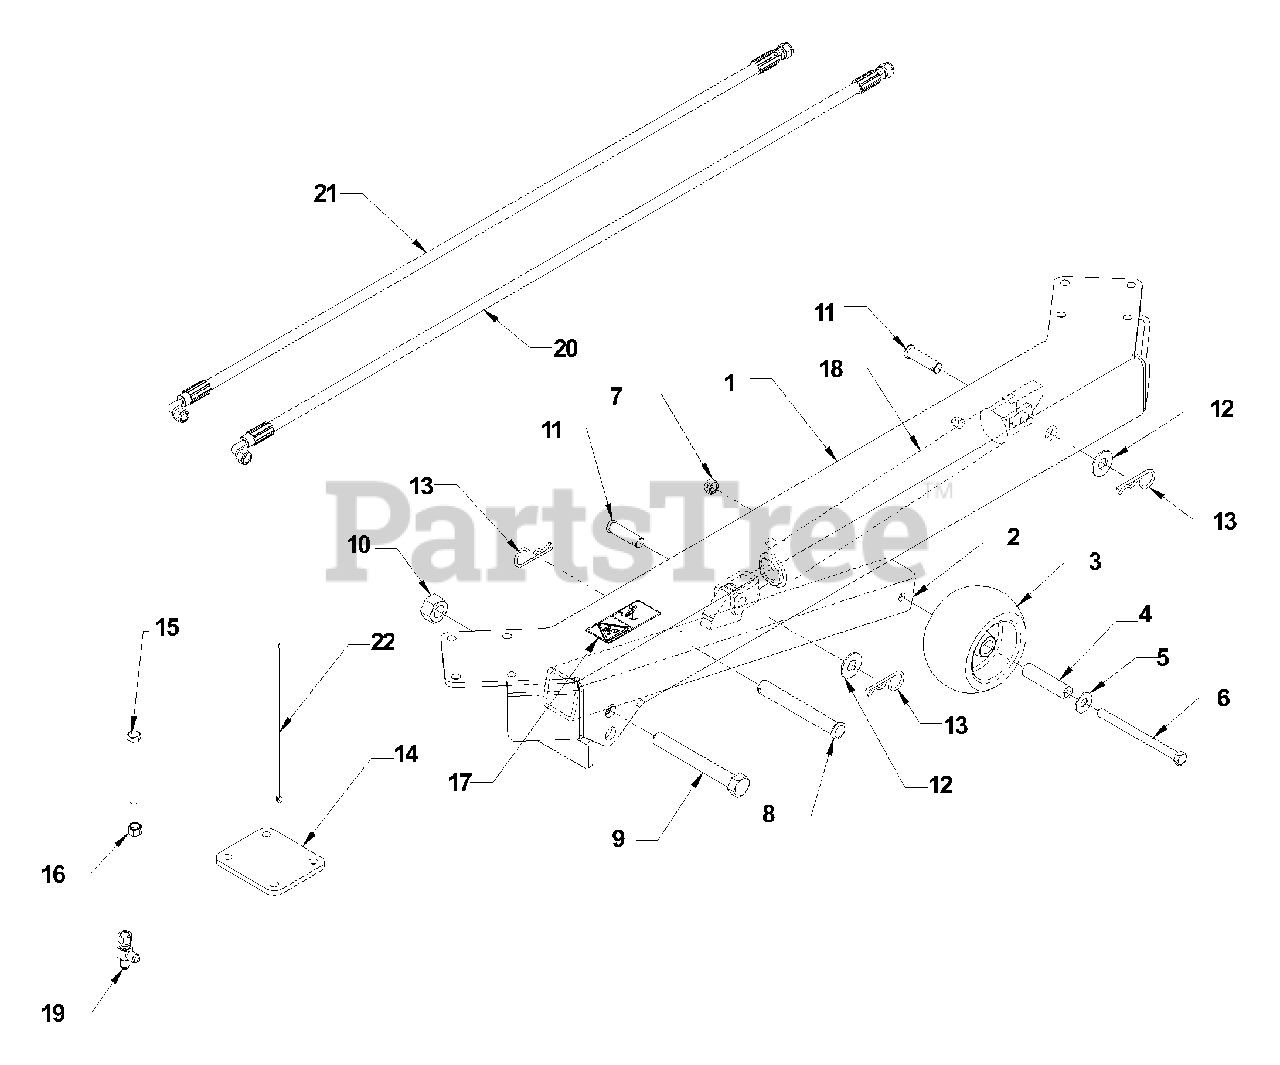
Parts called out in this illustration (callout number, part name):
1	Cross rail
3	Anti-scalp roller
5	Washer, 3/8
6	Screw, 3/8-16 x 5, GR 5
7	Nut, 3/8-16, center lock
8	Clevis pin, 5/8" x 4 3/4"
9	Screw, 5/8-11 x 5, GR 5
10	Nut, 5/8-11, nyloc
11	Clevis pin, 1/2" x 1 3/4"
12	Washer, 1/2
13	Hairpin, #4
14	Clamp plate
15	Screw, 3/8-16 x 3 1/2
16	Nut, 3/8-16, nyloc
17	Decal, cylinder safety
18	Hydraulic cylinder
19	Hydraulic tee
20	Hydraulic hose, 42"
21	Hydraulic hose, 39 1/2"
